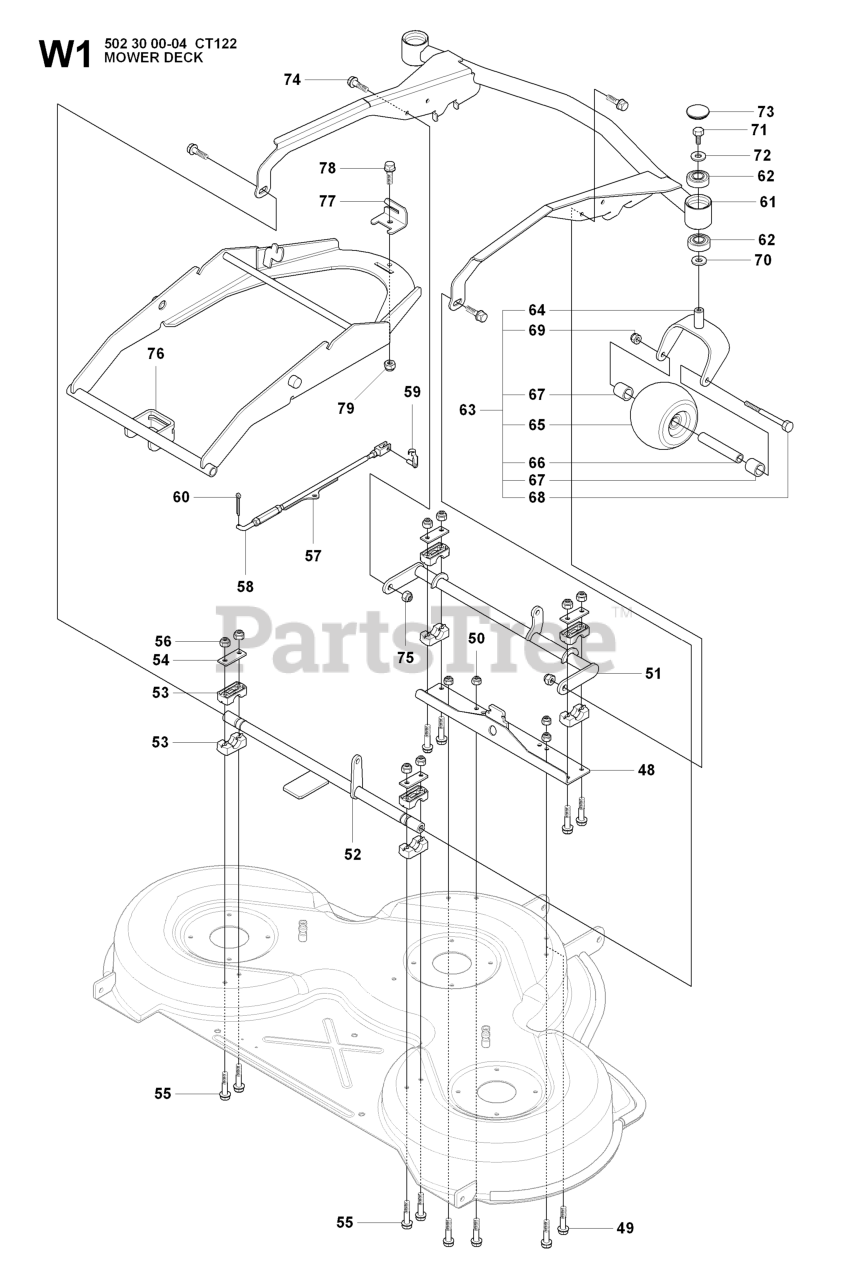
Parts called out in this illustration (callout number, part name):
50	LOCKNUT M8
56	LOCKNUT M8
58	PARALLEL ROD
62	BALL BEARING 6004-2RS1
63	PIVOT WHEELS
65	DECK ROLLER, FRONT
69	NUT
73	HUB CAP PIVOT WHEEL
75	LOCKNUT M8
79	LOCKNUT M8
